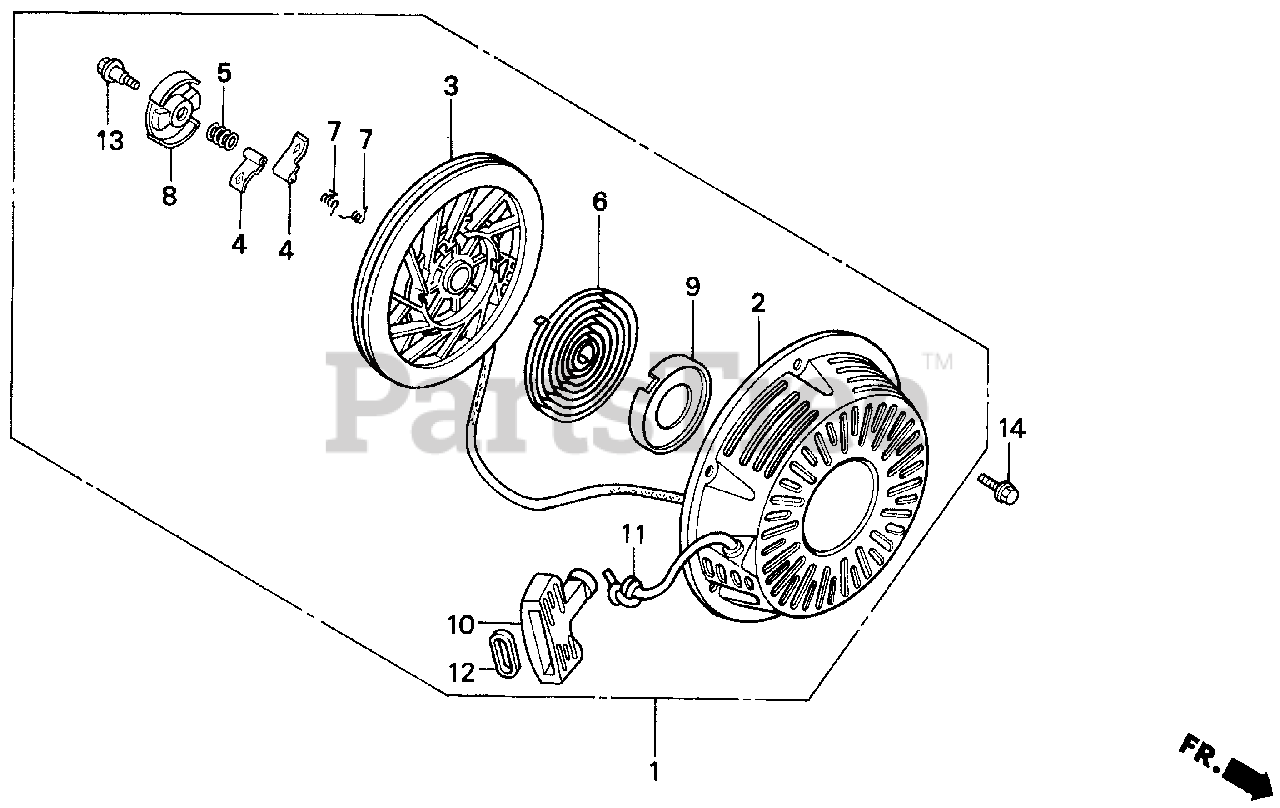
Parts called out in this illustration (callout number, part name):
1	STARTER ASSY., RECOIL *R8* (BRIGHT RED)
1	STARTER ASSY., RECOIL *NH1* (BLACK)
1	STARTER ASSY., RECOIL *T41* (BARTELL BLUE)
2	CASE, RECOIL STARTER *R8* (BRIGHT RED)
2	CASE, RECOIL STARTER *NH1* (BLACK)
2	CASE, RECOIL STARTER *T41* (BARTELL BLUE)
3	PULLEY, RECOIL STARTER
4	RATCHET, STARTER
5	SPRING, FRICTION
6	SPRING, STARTER RETURN
7	SPRING, RATCHET
8	RETAINER, SPRING
9	HOLDER, SPRING
10	GRIP, STARTER
11	ROPE, RECOIL STARTER (#5X55") (NA USE ALT:08550-ZG921-11)
11	ROPE, RECOIL STARTER (#5X55")
12	GRIP, REINFORCEMENT
13	SCREW, CENTER
14	BOLT, FLANGE (6X10)
14	BOLT, FLANGE (6X8)
